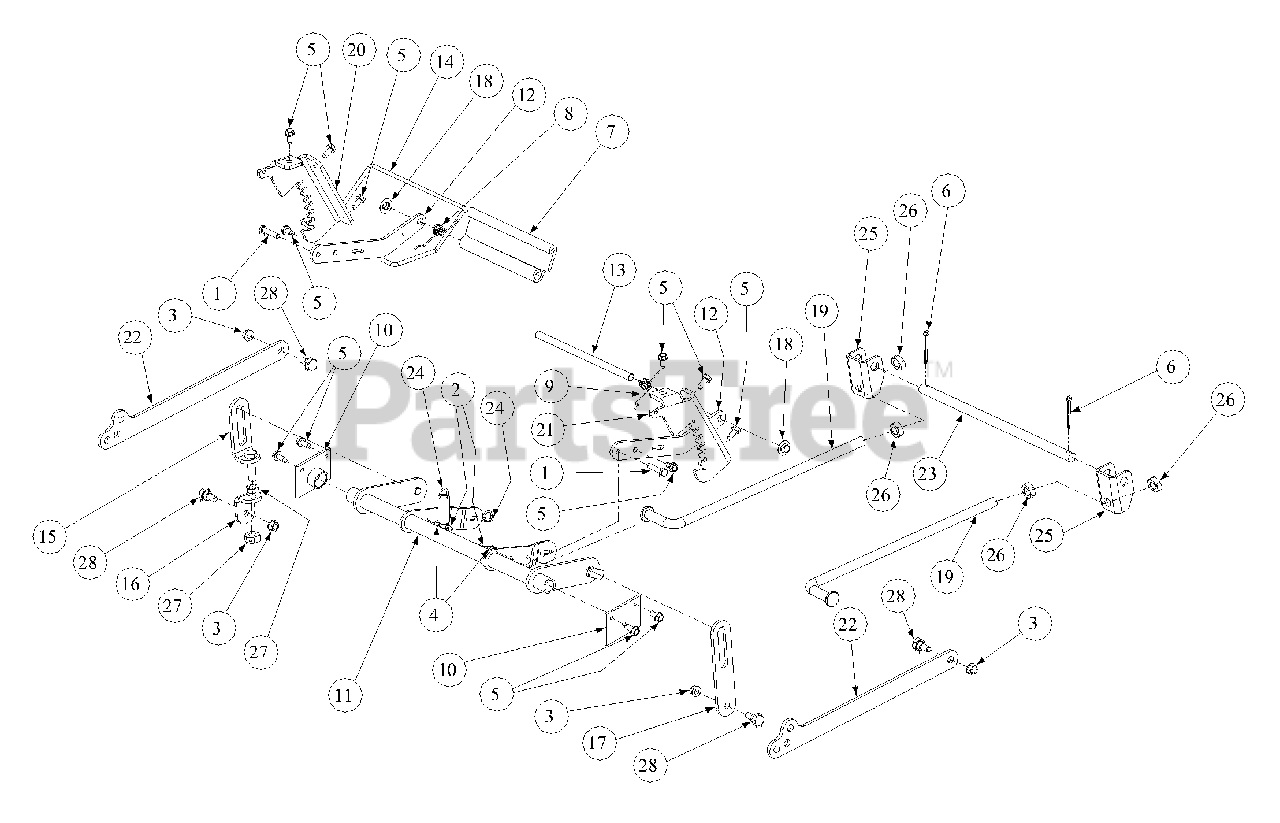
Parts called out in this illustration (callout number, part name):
1	Hex Cap Screw, 5/16-18 x 1-1/2
2	Nut, 5/16-18, Center Lock
3	Nut, 3/8-16, Hex Flange Lock
4	Hex Nut, 5/16-18
5	Self Tapping Screw, 5/16-18 x 3/4
6	Cotter Pin, 3/16 x 1-1
7	Deck Lift Handle
8	Deck Lift Spring, Left Hand
9	Deck Lift Spring, Right Hand
10	Lift Hub Assembly
11	Lift Shaft Assembly
12	Handle Lift Arm
13	Lift Handle Rod
14	Lift Rod Index
15	Upper Link Lift Assembly, Left Hand
16	Lower Lift Bracket, Left Hand
17	Link Lift PLate, Right Hand
18	Cap Lift Push Nut
19	Front Lift Rod
20	Lift Index Weldment, Left Hand
23	Front Lift Rod
24	Lift Spring
25	Front Lift Bracket (44" & 48")
26	Jam Nut, 5/8-11
27	Jam Nut, 1/2-20
28	Shoulder Screw, 3/8-16, .56 x .27
